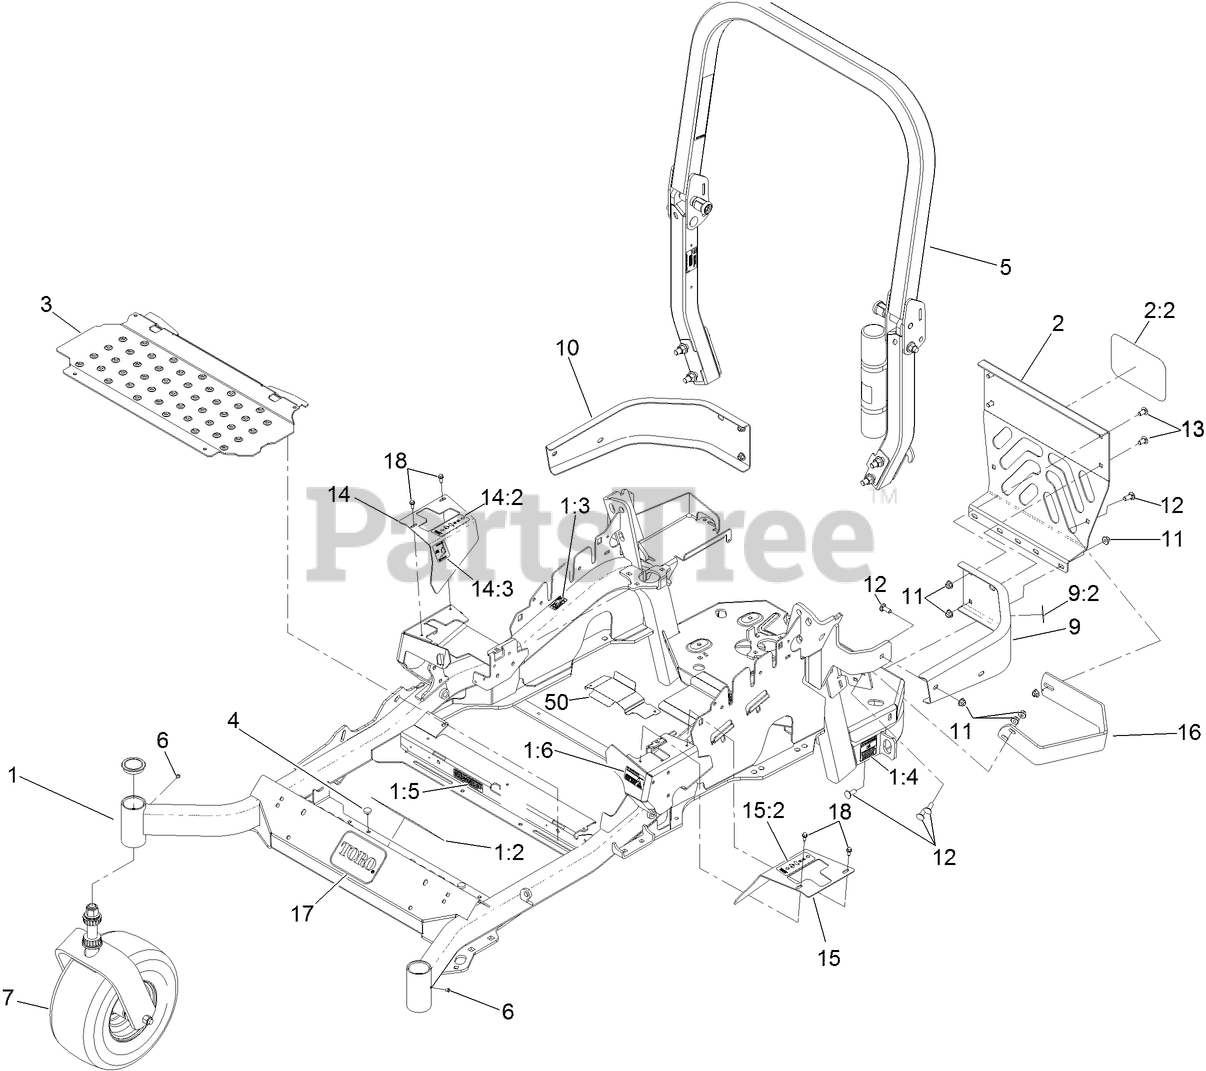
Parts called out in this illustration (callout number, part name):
1	MAIN FRAME ASM
1:2	DECAL-SLOPE
1:3	DECAL-CAUTION
1:4	DECAL-BELT DRIVE
1:5	DECAL-ARRESTER, SPARK
1:6	DECAL-FUEL FILL
2	REAR GUARD ASM
2:2	DECAL
3	FLOORPAN
4	BUMPER
5	ROPS ASM
7	Caster Wheel ASM
9	LH BUMPER ASM
9:2	DECAL-CAUTION
10	BUMPER-RH
11	NUT-HF, NI
12	SCREW-CARR
13	SCREW-CARR
14	RH MOTION CONTROL COVER ASM
14:2	DECAL-MOTION CONTROL
14:3	DECAL-PARK BRAKE
15	LH MOTION CONTROL COVER ASM
15:2	DECAL-MOTION CONTROL
16	GUARD-MUFFLER
17	DECAL
18	SCREW-HWH
50	GUARD-BELT
